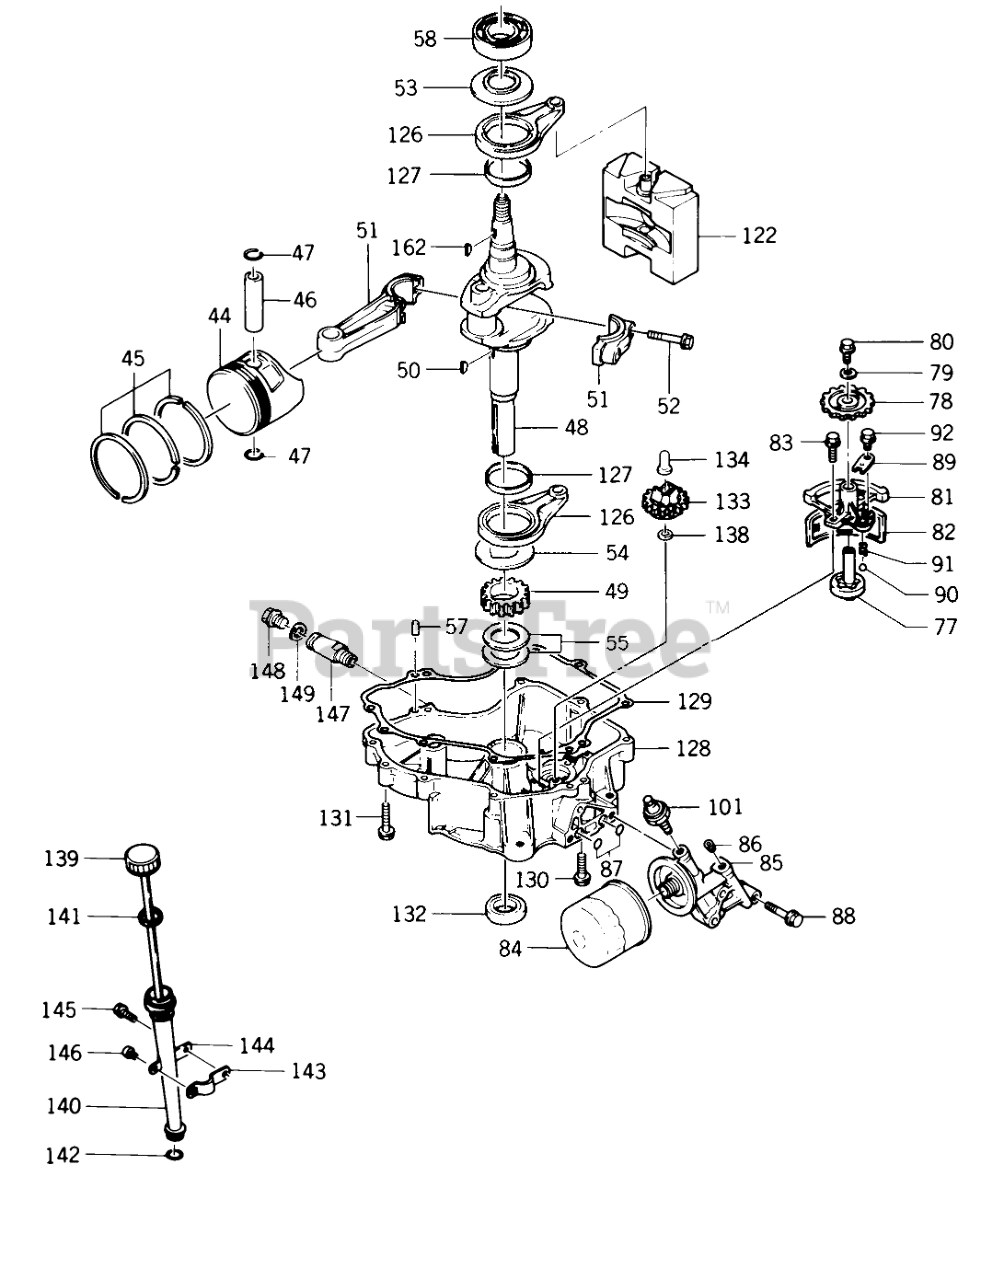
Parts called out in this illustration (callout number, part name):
44	PISTON STD
44	PISTON 0.S.-.25MM
44	PISTON 0.S.-.50MM
44	PISTON 0.S.-.75MM
45	RING PISTON-STD
45	Piston Ring Set-.010 Over Size
45	RING-PISTON-.020
45	RING PISTON-.030
46	PIN PISTON
47	RING-SNAP
48	ASSY-CRANK SHAFT
49	GEAR-HELICAL
50	KEY-WOODRUFF
51	Connecting Rod Assty-Standard Size (Includes item 52)
51	Connecting Rod Assty-0.50mm Under Size (Includes item 52)
52	BOLT-CON ROD
53	SPACER
54	SPACER
55	SHIM-1.18
55	SHIM-1.215
55	SHIM-1.25
55	SHIM-1.60
55	SHIM-1.32
55	SHIM-1.355
55	SHIM-1.425
55	SHIM-1.46
55	SHIM-1.495
55	SHIM-1.53
55	SHIM-1.565
55	SHIM-1.635
55	SHIM-1.67
55	SHIM-1.705
55	SHIM-1.74
58	BEARING-BALL
77	OIL PUMP ASS'Y
78	GEAR-HELICAL COIL
79	WASHER
80	Bolt
81	PUMP COVER COMP
82	FILTER OIL INTERNAL
83	BOLT (8 X 25)
84	Filter-Oil
85	PIPE COMP
87	O-RING
88	BOLT (8 X 40)
89	PLATE
90	BALL-STEEL 5/16
91	SPRING
92	BOLT-FLANGED
101	SWITCH-OIL PRESSURE
122	WEIGHT COMP
126	ASSY-ROD
127	BEARING
128	COVER-CRANKCASE
129	GASKET
130	BOLT (8 X 30)
131	BOLT (8 X 45)
132	SEAL OIL
133	GOVERNON
134	SLEEVE-GOVERNOR
138	WASHER
139	GAGE-OIL
140	TUBE-FILLER
141	GASKET
142	O-RING
143	CLAMP
144	CLAMP
145	Bolt
146	SCREW (6 X 8)
147	JOINT
148	PLUG DRAIN
149	GASKET
162	KEY-WOODRUFF
